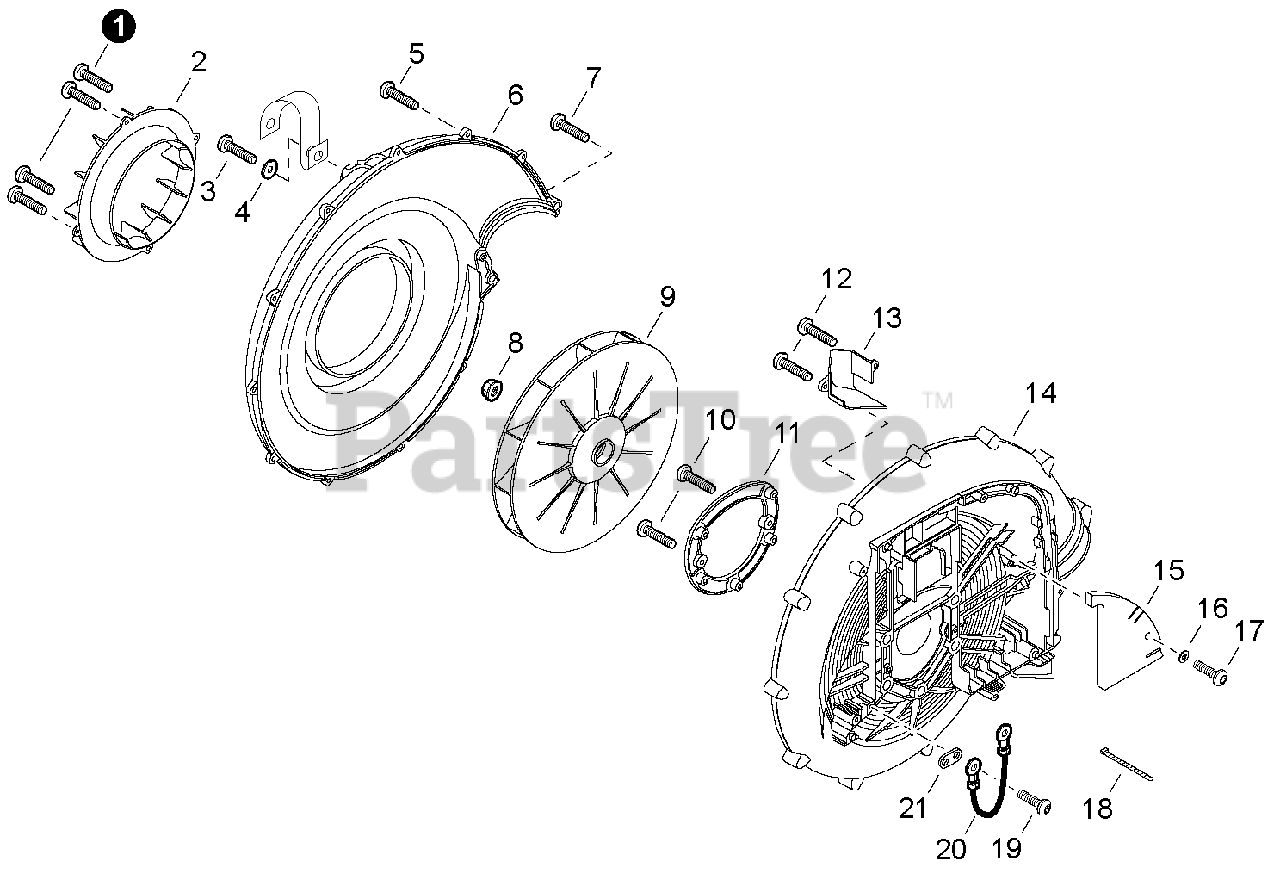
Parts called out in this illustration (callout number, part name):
1	BOLT, TORX 5×16
2	DEFLECTOR, AIR
3	BOLT, TORX 5×20
4	WASHER 5.5×16×2T
5	BOLT, TORX 5×20
6	COVER, FAN CASE
7	BOLT, TORX 5×20
8	NUT, FLANGE 10×1.25
9	FAN, BLOWER
10	BOLT, TORX 5×16
11	PLATE, ENGINE
12	BOLT, TORX 5×16
13	COVER, AIR GUIDE
14	CASE, FAN
15	PAD, FOAM
16	WASHER 5.2×14×T3
17	BOLT, TORX 5×16
18	STRAP, TIE
19	BOLT, TORX 5×16
20	LEAD L= 195 MM
21	PLATE, EYE
